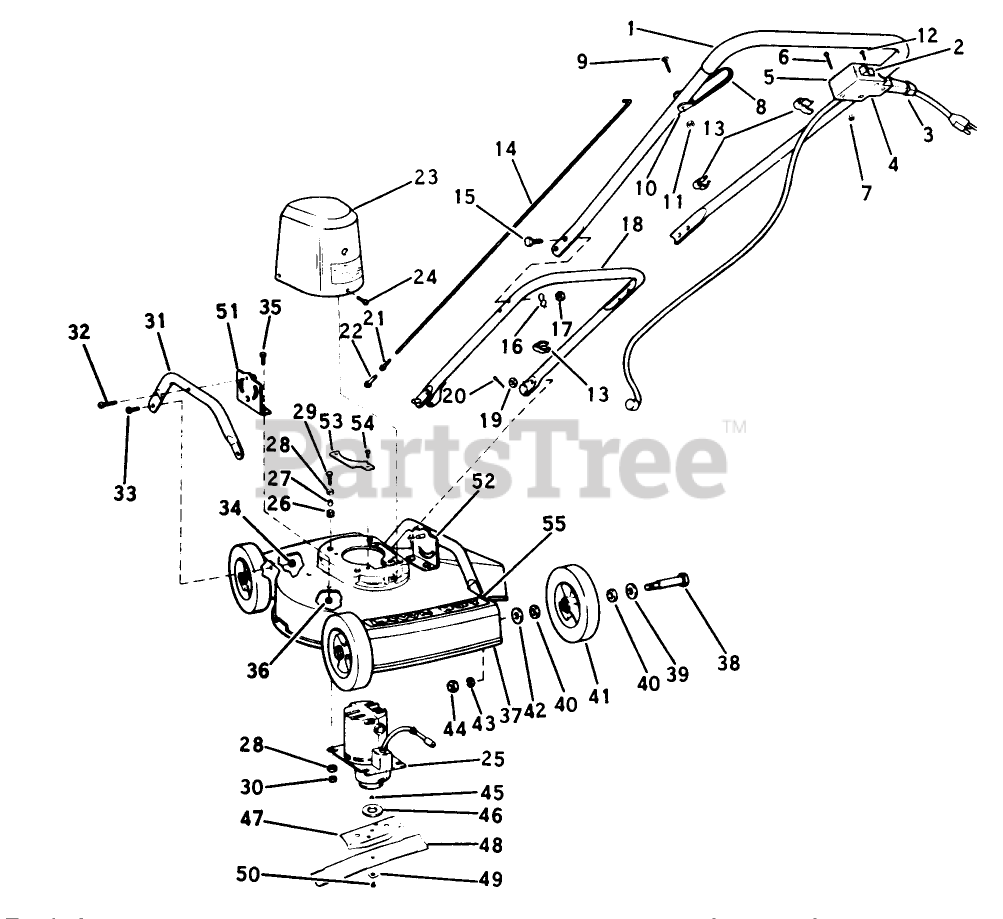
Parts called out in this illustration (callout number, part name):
2	Switch Assembly
9	Screw-Handle Release
12	Screw-Ground
35	SCREW S
42	WASHER WROUGHT
43	WASHER, LOCK
49	LOCKWASHER
52	Bracket and Pin Assy-RH
